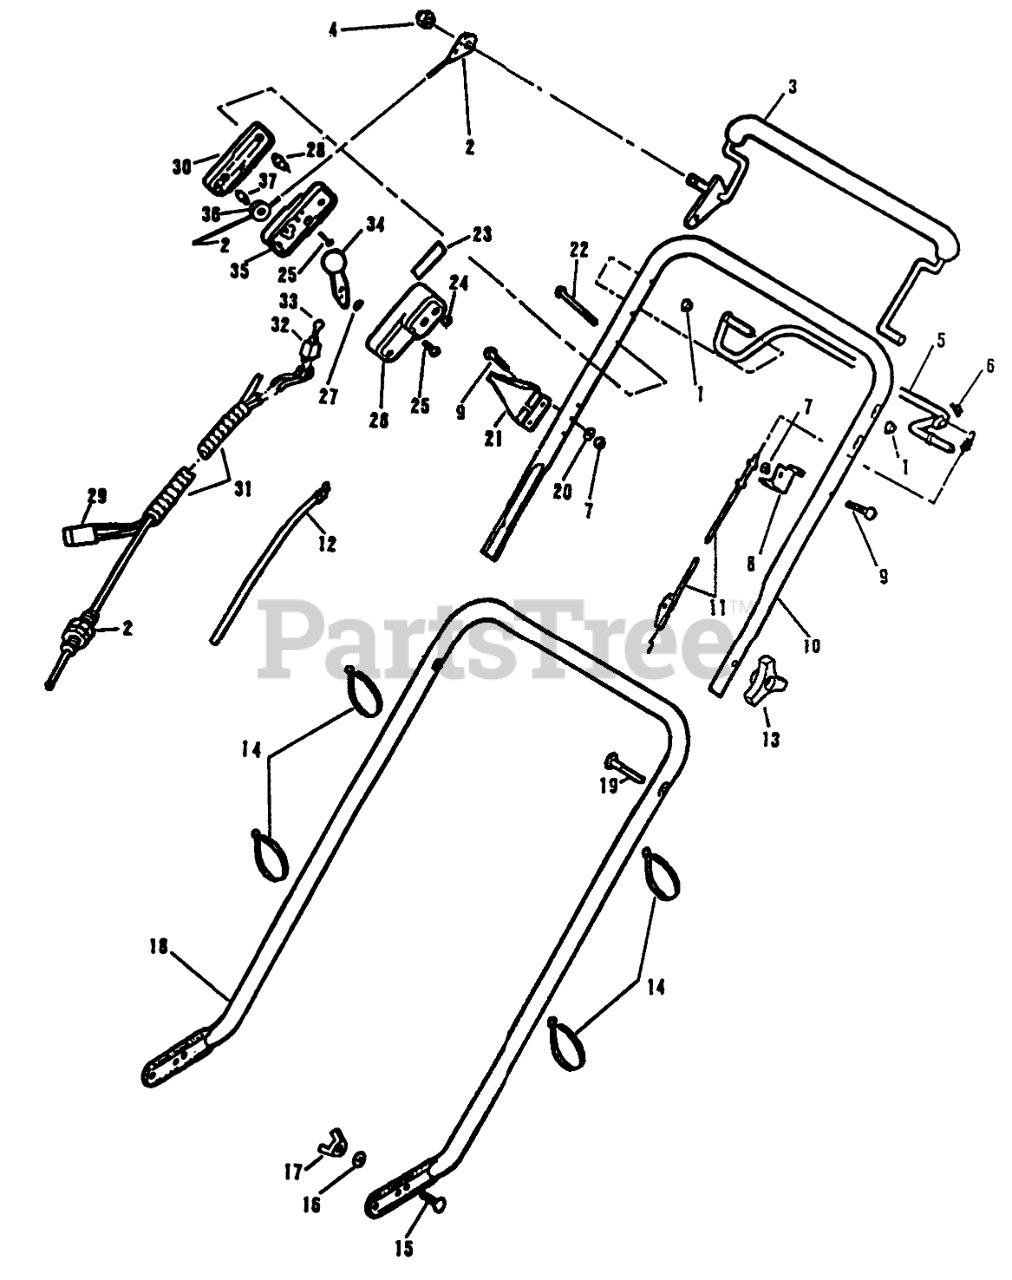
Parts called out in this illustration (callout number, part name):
1	NUT-PUSH
2	CONTROL CABLE
3	CONTROL LEVER ARG
4	NUT ACORN
5	C'TROL LEVER ARGO
6	NUT
7	LOCKNUT E
8	ANCHOR C'DUIT TRO
9	SCREW
10	Handle-Top
11	CABLE - CONTROL
12	CABLE TH'TTLE WES
13	Knob
14	TIE-CABLE
15	Bolt
16	WASHER LOCK B'GER
17	NUT WING
18	Handle-Lower
19	Screw
20	WASHER
21	GUIDE - ROPE
22	SCREW
23	DECAL-THROT CONTRL
24	NUT C/LOCK E
25	SCREW
26	CASE THROTTLE
27	WASHER-SPRING
28	COLUMN
29	Wire Harness Assembly
30	OUTER CONTROL CASE
31	SPIRAL TUBING MMN
32	Key Switch
33	KEY
34	LEVER&KNOB AY WES
35	CENTER CONTROL CASE
36	PULLEY PL
37	PIN SKF
